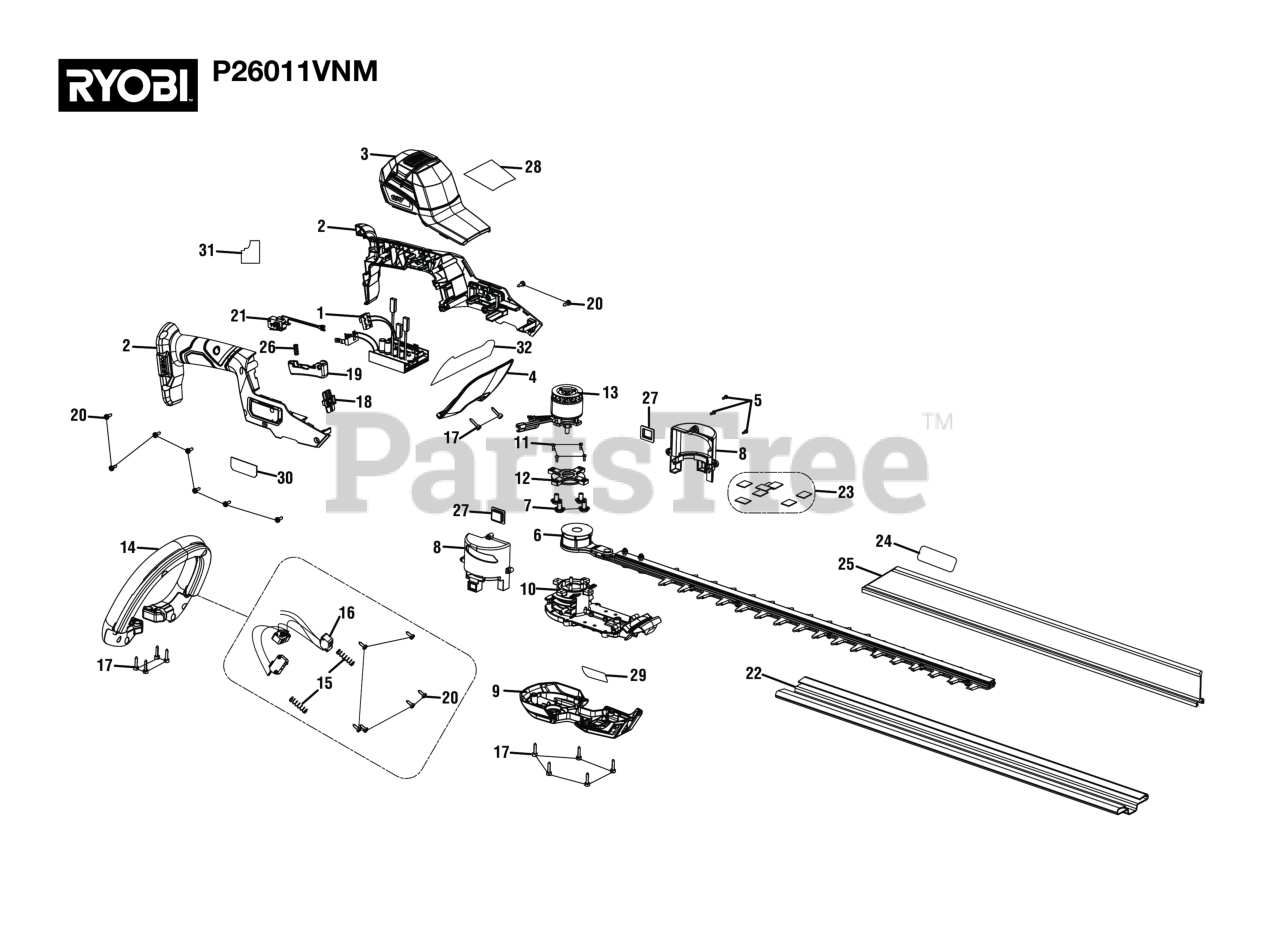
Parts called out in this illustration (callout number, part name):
1	Motor Controller, Switch and Battery Connector Assembly
2	Housing Assembly
3	Top Cover Assembly
4	Guard Assembly
5	Screw (M3 x 8 mm, Pan Hd., Pan Hd)
6	Gear and Blade Assembly
7	Screw w/Washer (M4 x 8 mm)
8	Motor Housing Assembly
9	Gear Box Cover Assembly
10	Gear Box Base Assembly
11	Screw (M3 X 8 mm)
12	Motor Plate
13	Motor Assembly
14	Front Handle Assembly
15	Spring,Handle Cover, Dia. 7, SWC
16	Switches and Wire Assembly
17	Screw w/Washer (M4 x 16 mm, T25 Torx Truss Hd.)
18	Speed Selector
20	Screw (M4.2 x 12 mm, T20 Torx Pan Hd.)
21	Micro Switch
24	Warning Label
25	Hedge Sweep Assembly
27	Rubber Plate
28	Warning Label
29	Whisper Label
30	Data Label
32	Icon Danger Label
